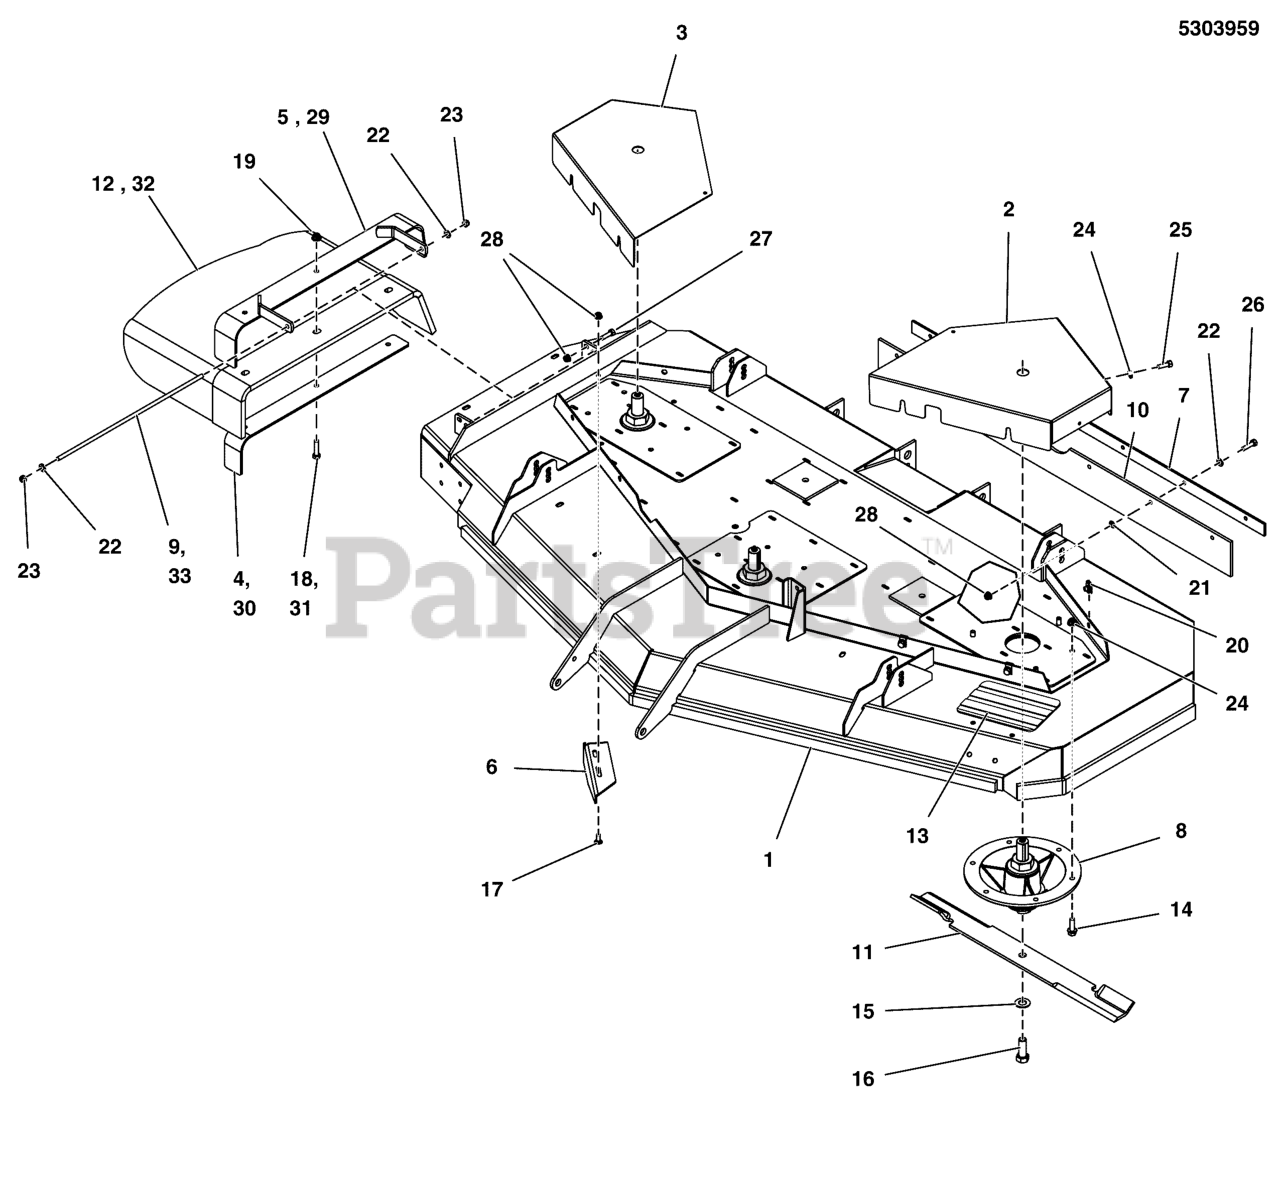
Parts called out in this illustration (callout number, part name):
1	* DECK SHELL W/ DECALS, 72, 3200-DOM
1	* DECK SHELL W/ DECALS, 72, 3200, ANSI-EXP
2	GUARD, LH, IS3200Z-72 - RED
3	GUARD, RH, IS3200Z-72 - RED
4	SUPPORT, DICHARGE CHUTE, 61/72 - BLK
5	WELD, FRAME, CHUTE, 72 - BLK
6	PLATE, DEFLECTOR, 72 - BLK
7	PLATE, SUPPORT, 72" - BLK
8	SPINDLE ASSEMBLY
9	ROD, MOUNT, CHUTE, 72, CZ
10	FLAP, STRIPER, 72 DECK
11	BLADE SET, 72 DECK (SET OF THREE)
12	CHUTE, DISCHARGE, BEND RUBBER (SV)
13	SAFETY WALK, 9.75 X 6.00
14	BOLT, 3/8-16 X 1-1/4, FLANGE, GD 5, CZ
15	WASHER, BLADE BOLT, 9/16" F436, CZ
16	BOLT, 5/8-11 X 1-3/4 GD8
17	BOLT, 5/16-18 X 3/4, CARRIAGE
18	BOLT, 3/8-16 X 1-1/2" GD5 CZ
19	NUT, 3/8-16 HEX NYLOCK FLANGE
20	BODY CLIP, 5/16-18-7GA MATERIAL
21	5/16 PUSH-ON NUT RETAINER, STL, CZ
22	WASHER, 5/16" SAE
23	NUT, 5/16-24 HEX NYLON LOCK
24	WASHER, 5/16 F436 FLAT
25	BOLT, 5/16-18 X 1 GD5 CZ
26	BOLT, 5/16-18 X 1-1/4 GD5 CZ
27	BOLT, 5/16-18 X 3/4 GD5
28	NUT, 5/16-18 HEX NYLOCK FLANGE
29	MOUNT
30	SUPPORT, DISCHARGE CHUTE - BLK
31	BOLT, 3/8-16 X 1-1/2, CARRIAGE, GD5, CZ
32	CHUTE, RUBBER DISCHARGE
33	ROD, MOUNT, CHUTE 61, CZ
